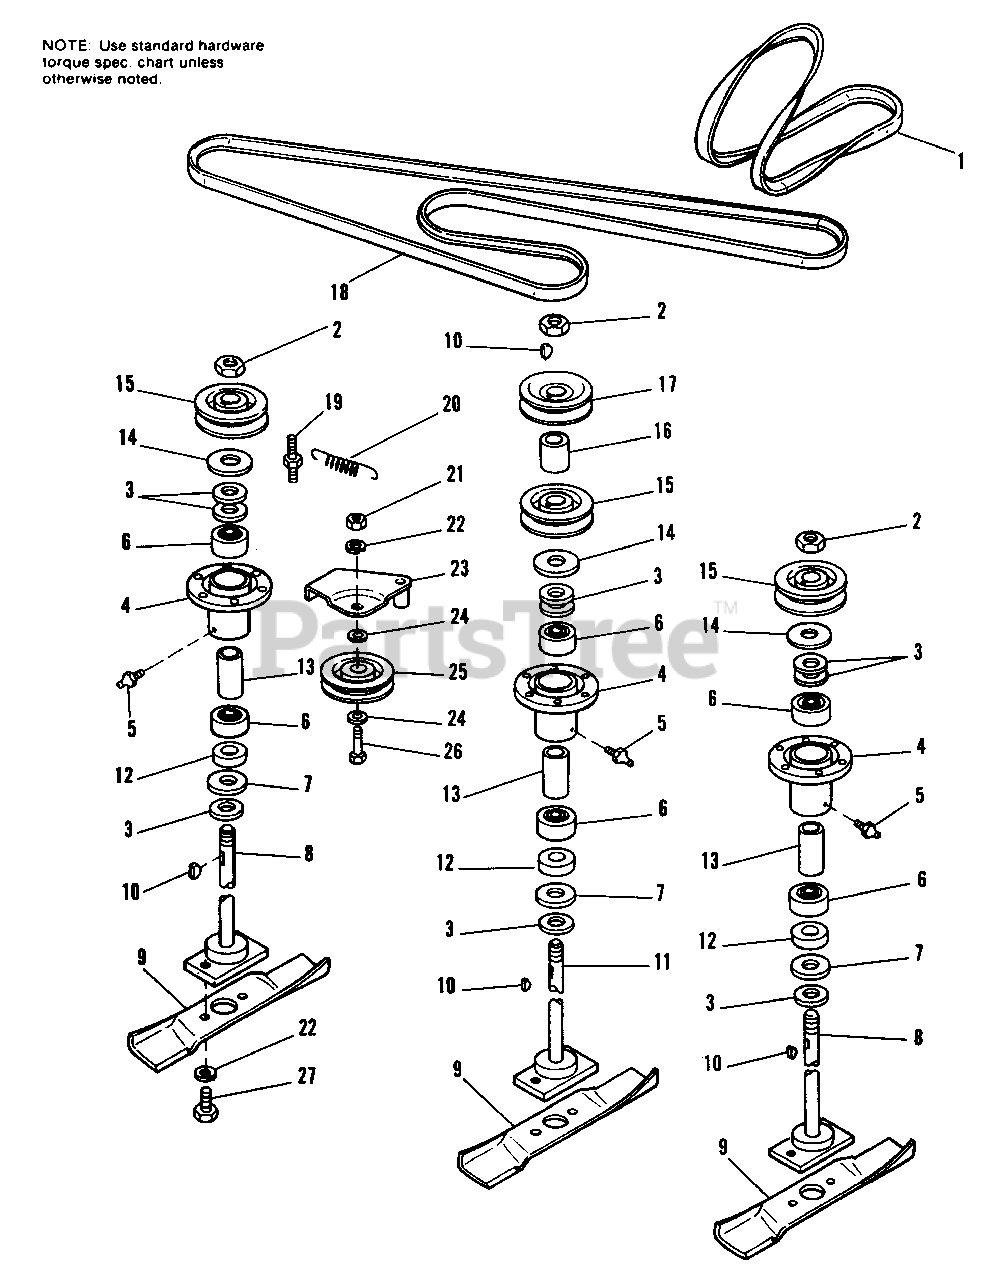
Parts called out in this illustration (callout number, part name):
1	V-BELT
2	LOCKNUT, Hex, 3/4-16
4	TUBE ASSY., Arbor
5	FITTING, Grease
6	BEARING, Ball
8	ARBOR ASSY.
10	KEY, Woodruff, 3/16 x 5/8
11	ARBOR ASSY., Drive
17	PULLEY, Cross Drive
18	V-BELT
20	SPRING, Torsion
21	NUT, Hex, Full, 3/8-16
22	LOCKWASHER, 3/8
23	LEVER ASSY.
24	WASHER, Plain, 5/16
25	PULLEY, Idler
26	SCREW, Special
27	CAPSCREW, Hex Hd., 3/8-16 x 5/8
